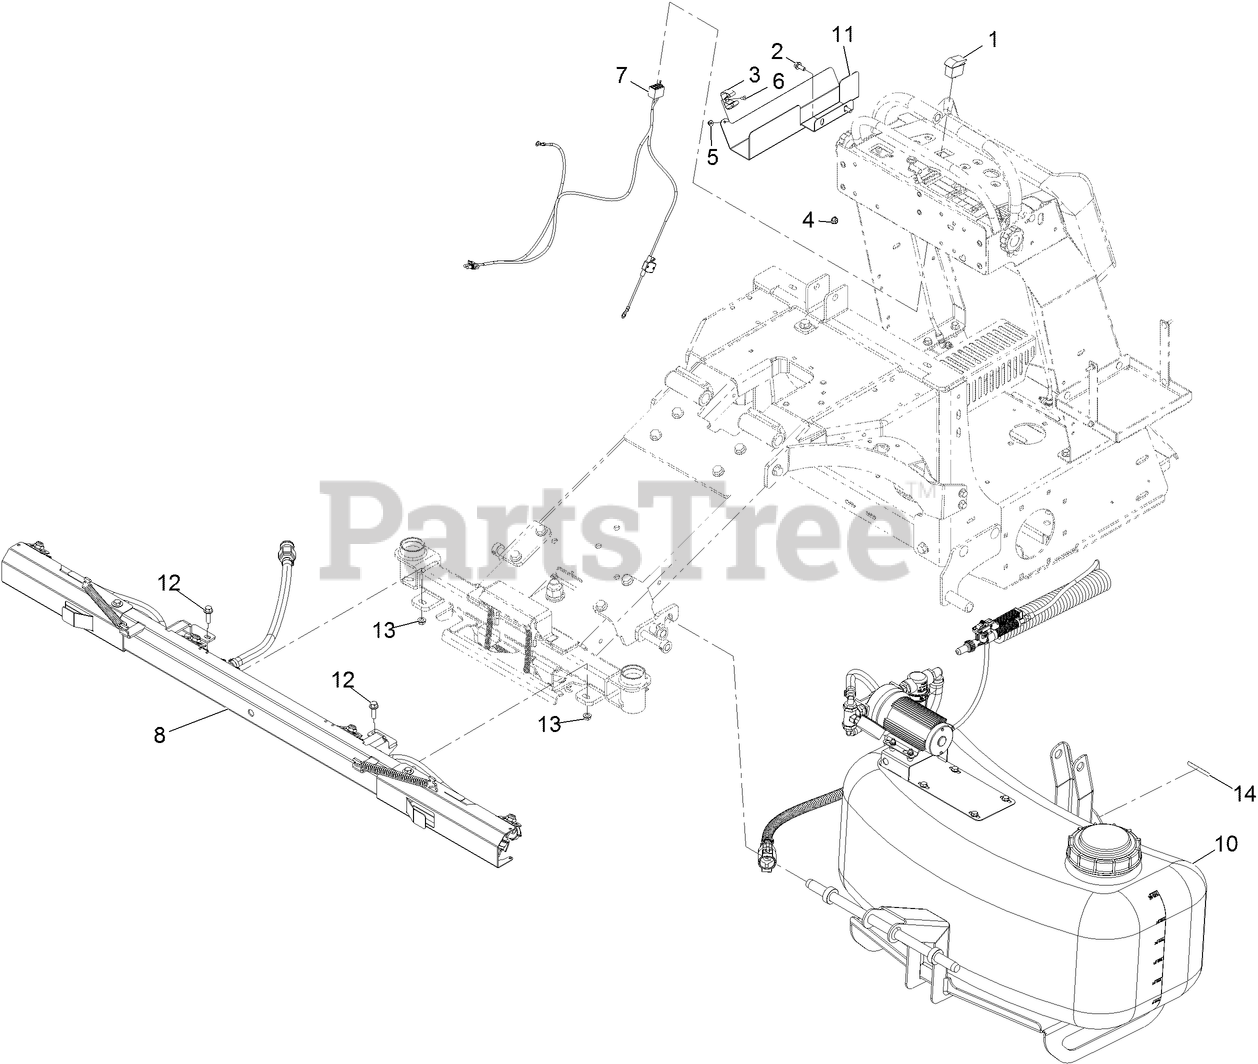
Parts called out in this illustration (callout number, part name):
1	SWITCH-ROCKER
2	SCREW-HHF
3	Holder-Tool, Clip
4	Nut-Hex Flange
5	Nut-Hex Flange
6	Screw-HSBH
7	HARNESS-ACCESSORY
8	Boom-Spray 96"
10	ASM, TANK, ISO, 30GAL ATT
11	Tray-Spray Gun
12	SCREW-HHF
13	NUT-HHF, WHIZ
14	DECAL-WARNING
